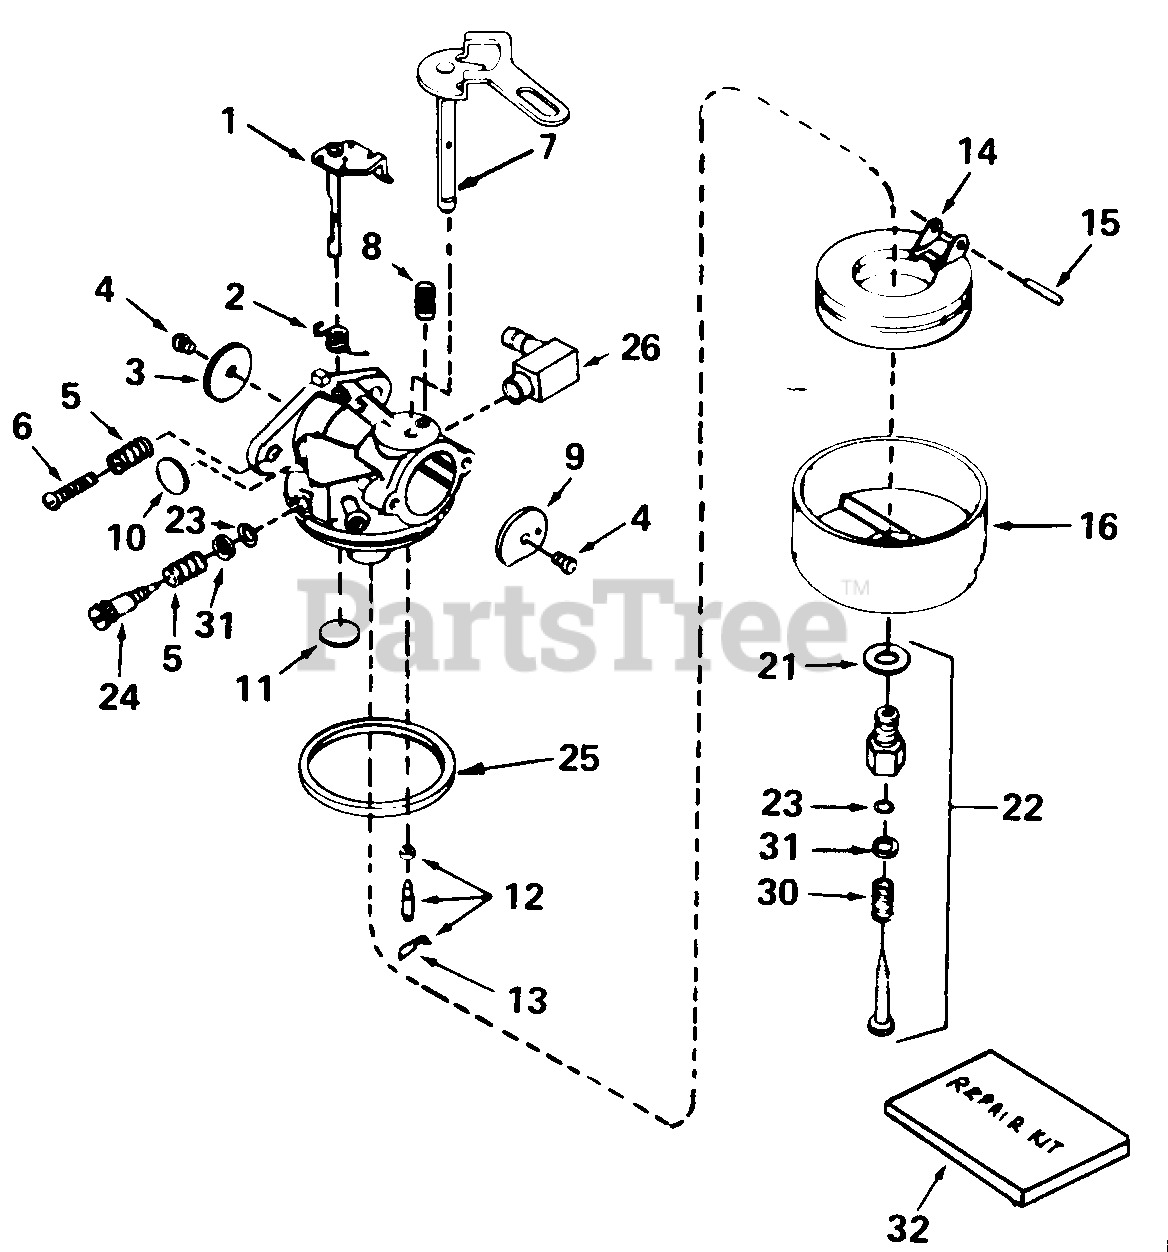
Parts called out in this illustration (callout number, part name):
1	Shaft & Lever Ass'y., Throttle
2	Spring, Throttle Return
3	Shutter, Throttle
4	Screw, 4-40 x 3/16
5	Spring,Idle Regulating Screw
6	Screw, Idle Regulating
7	Shaft & Lever Ass'y., Choke
8	Spring,Choke Stop
9	Shutter Choke
10	Plug, Welch
11	Plug, Welch
12	Inlet Needle Seat & Clip Ass'y.
13	Clip Inlet Needle
14	Float, arburetor
15	Shaft,Float
16	Bowl, Float
21	Gasket Bowl-to-Body
22	Adjustment Screw Ass'y., Main
23	"O"-Ring, Adjustment Screw
24	Screw, Idle Adjustment
25	Gasket Bowl-to-Body
26	Fitting,Fuel Inlet
30	Spring, Main Adjustment Screw
31	Washer, Flat
32	Repair Kit
